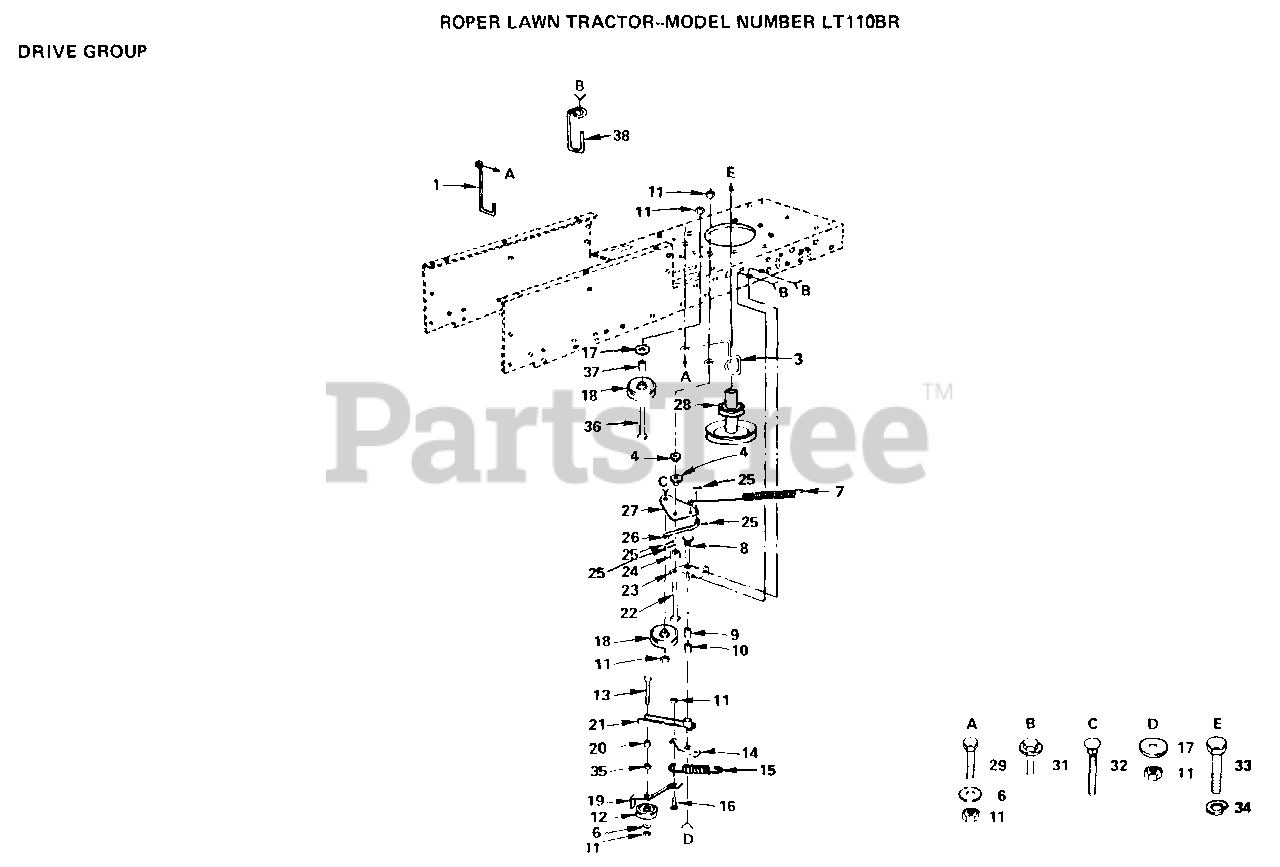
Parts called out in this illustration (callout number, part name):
3	GUIDE BELT PLY LT
6	WASHER
7	SPRING CLUTCH LT
8	BOLT
12	IDLER.FLAT.GTV
13	BOLT
15	SPRING EXT LT
16	BOLT
17	WASHER
18	IDLER-FLAT LT
21	ARM IDLER ASSY LT
23	BRACKET SUPT LT
24	SPACER LT
25	COTTER PIN
29	BOLT
31	SCREW
32	BOLT
34	LOCKWASHER
35	NUT.HEX.3/8-16UNC
36	BOLT
37	SPACER SPLIT LTV
